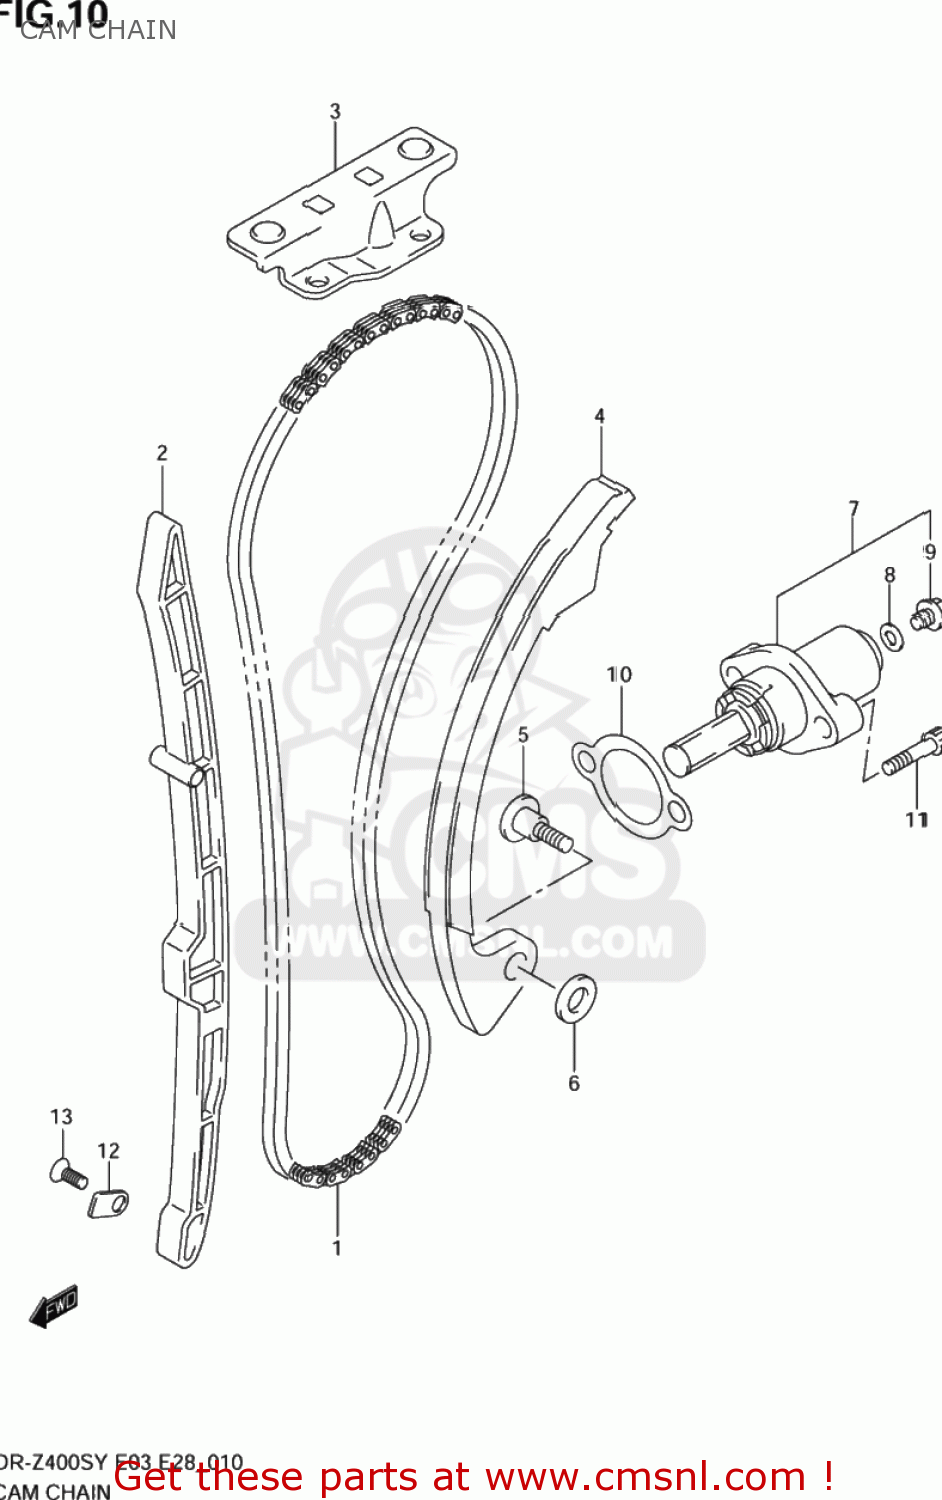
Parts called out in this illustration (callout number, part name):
1	CHAIN COMP,CAMSHAFT DRIVE
2	GUIDE,CAM CHAIN NO.1
3	GUIDE,CAM CHAIN NO.2
4	TENSIONER,CAM CHAIN
5	BOLT,CAM CHAIN TENSIONER
6	WASHER
7	ADJUSTER ASSY,TENSIONER
8	GASKET,TENSIONER ADJUSTER (NAS)
9	PLUG,FR TENSIONER ADJ
10	GASKET,TENSIONER ADJUSTER (NAS)
11	BOLT,CL.COVER
12	RETAINER,CAM CHAIN GUIDE NO.1
13	SCREW(6X12)
